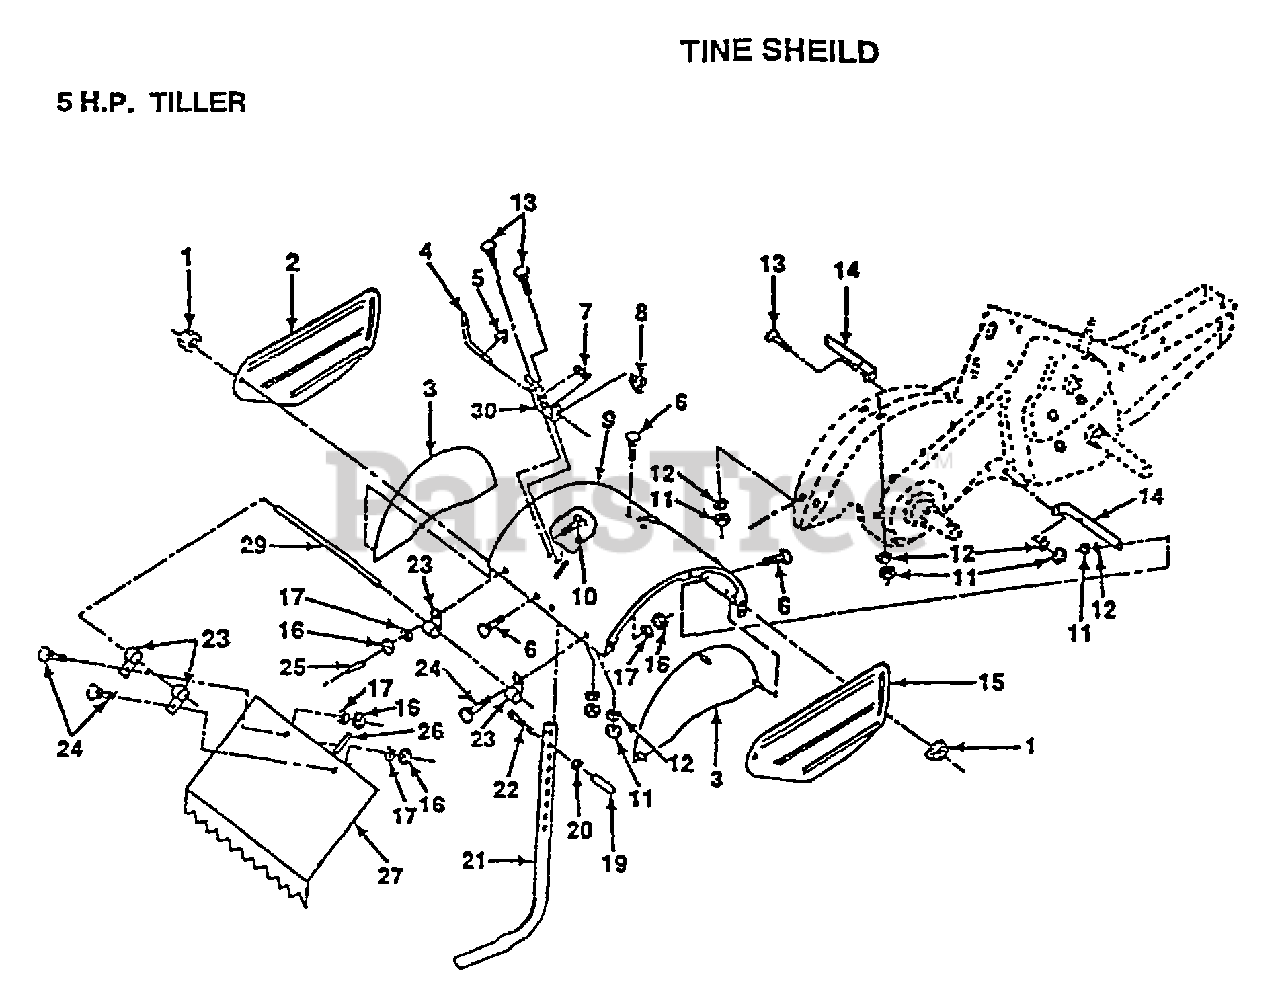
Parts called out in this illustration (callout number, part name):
1	NUT
2	SHIELD.SD.OUT.LH
4	STAKE PIN TI
5	KLIP RING TI
6	BOLT
7	SPRING TI
8	SPRING CRT
9	SHLD TINE
11	LOCKWASHER
12	NUT.HEX.5/16-18
13	BOLT
14	BRKT SHIELD TINE
17	LOCKWASHER
19	GRIP CRT
20	NUT.HEX.3/8-16UNC
22	BOLT
23	HINGE CRT
24	BOLT
25	VINYL CAP TI
26	PAD IDLER TI
29	PIN HINGE
30	LATCH BRACKET TI
31	BOLT CRT
